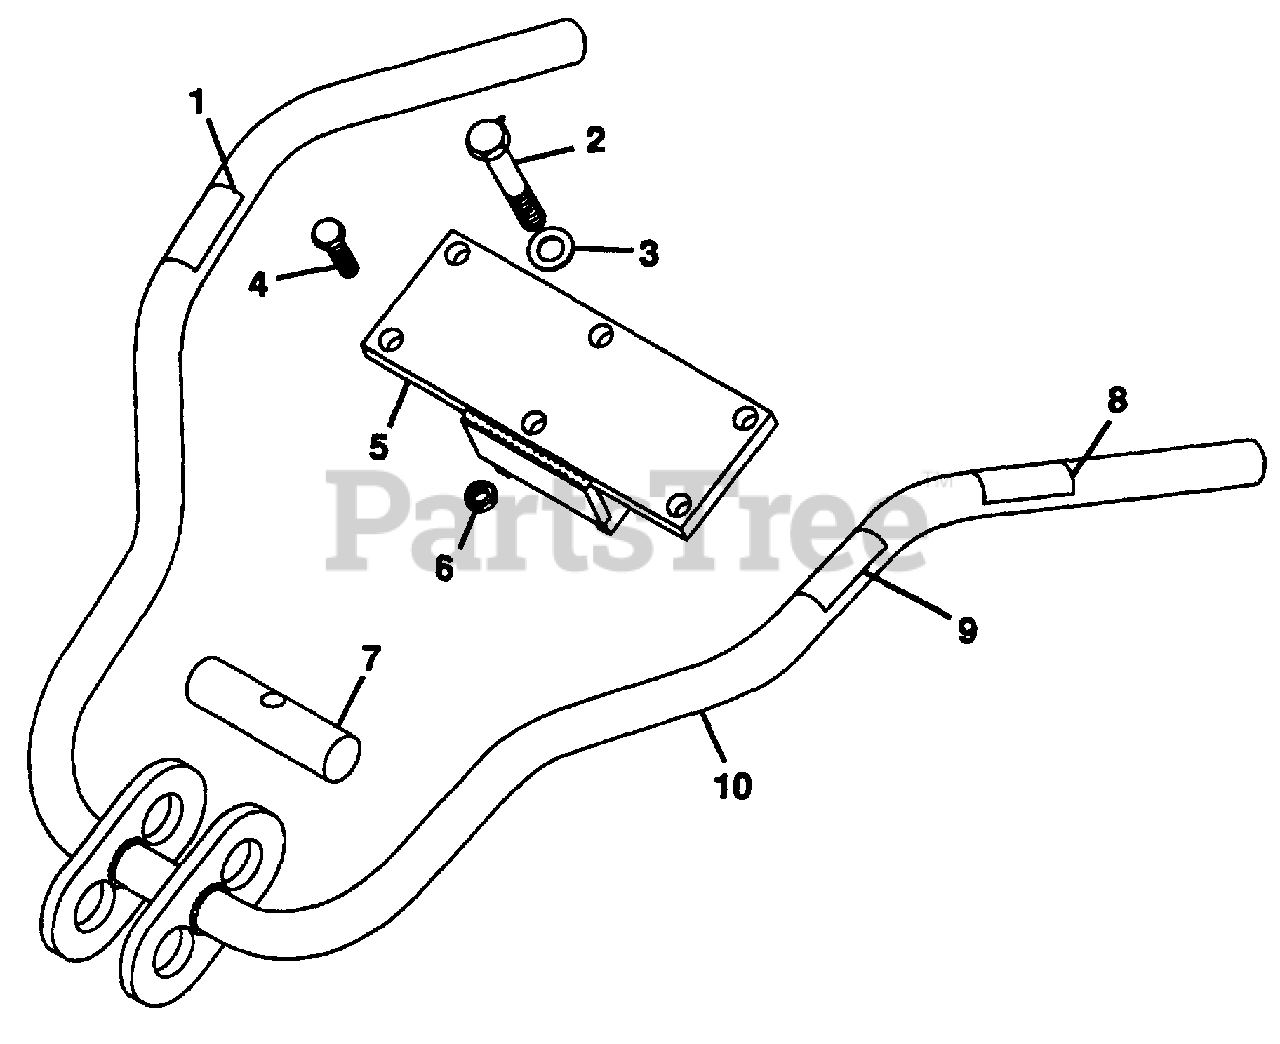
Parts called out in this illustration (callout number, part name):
1	Decal, Gear Shift
2	Bolt, Hex 1/2-13x3.00 Grade 8
3	Washer, Lock 1/2 Reg.
4	Bolt, Hex 3/8-16x1.25 Grade 8
5	Weldment, Handlebar Bracket
6	Nut, Lock 3/8-16
7	Pin
8	Decal, Throttle
9	Decal, Fwd-Rev
10	Weldment, Handlebar
NS	Tie Wrap, Black
